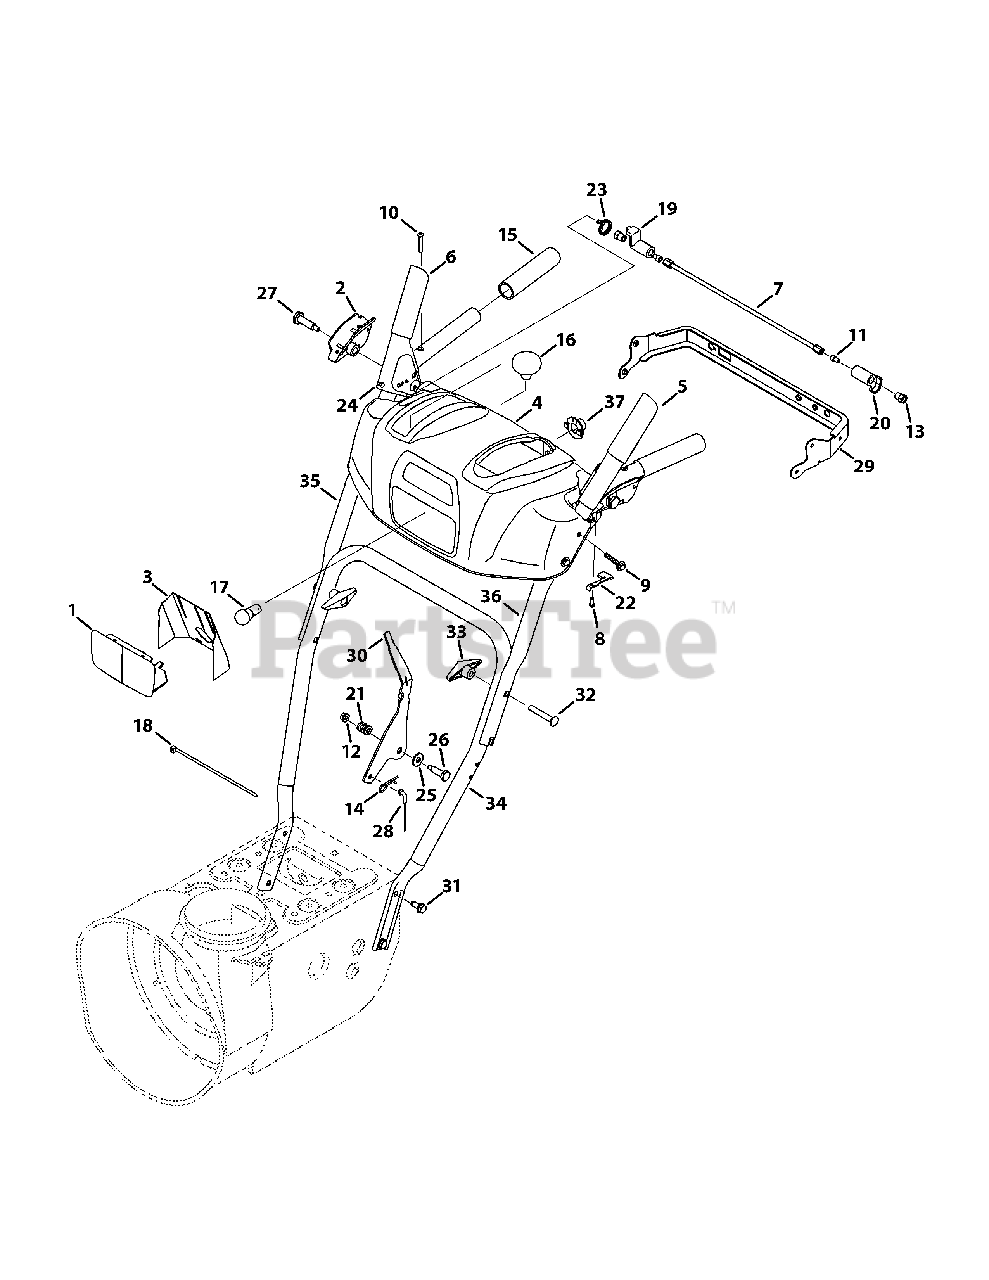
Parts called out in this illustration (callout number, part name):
2	Handle Clutch Lock - RH
2	Handle Clutch Lock - LH
3	Lens Reflector Label
4	T-Style Panel Ass’y, (inc. Ref. 1 & 3)
5	Handle Engagement Assembly LH
6	Handle Engagement Assembly RH
8	Screw, Plastite, 8-16 x .50
9	Screw, 1/4-20 x 1.625
10	Screw, #10-24 x 1.375
11	Screw, Socket, 1/4-20 x .50
12	Flange Lock Nut, 1/4-20
13	Shoulder Nut, 1/4-20
14	Click Pin
15	Handle Grip
16	Shift Knob
18	Cable Tie
20	Clutch Lock Cam
21	Compression Spring
22	Clutch Lock Spring
23	Torsion Spring
24	Rubber Bumper
25	Flat Washer, .385 x .87 x .06
26	Shoulder Screw, .374 x 1.05
27	Shoulder Screw, 1/4-20 x 1.345
28	Speed Selector Cable
29	Panel Bracket
31	Screw, 5/16-18 x .750
32	Carriage Screw, 5/16-18 x 2.25
33	Wing Knob
34	Lower Handle
35	Upper Handle RH
36	Upper Handle LH
37	Light Socket
